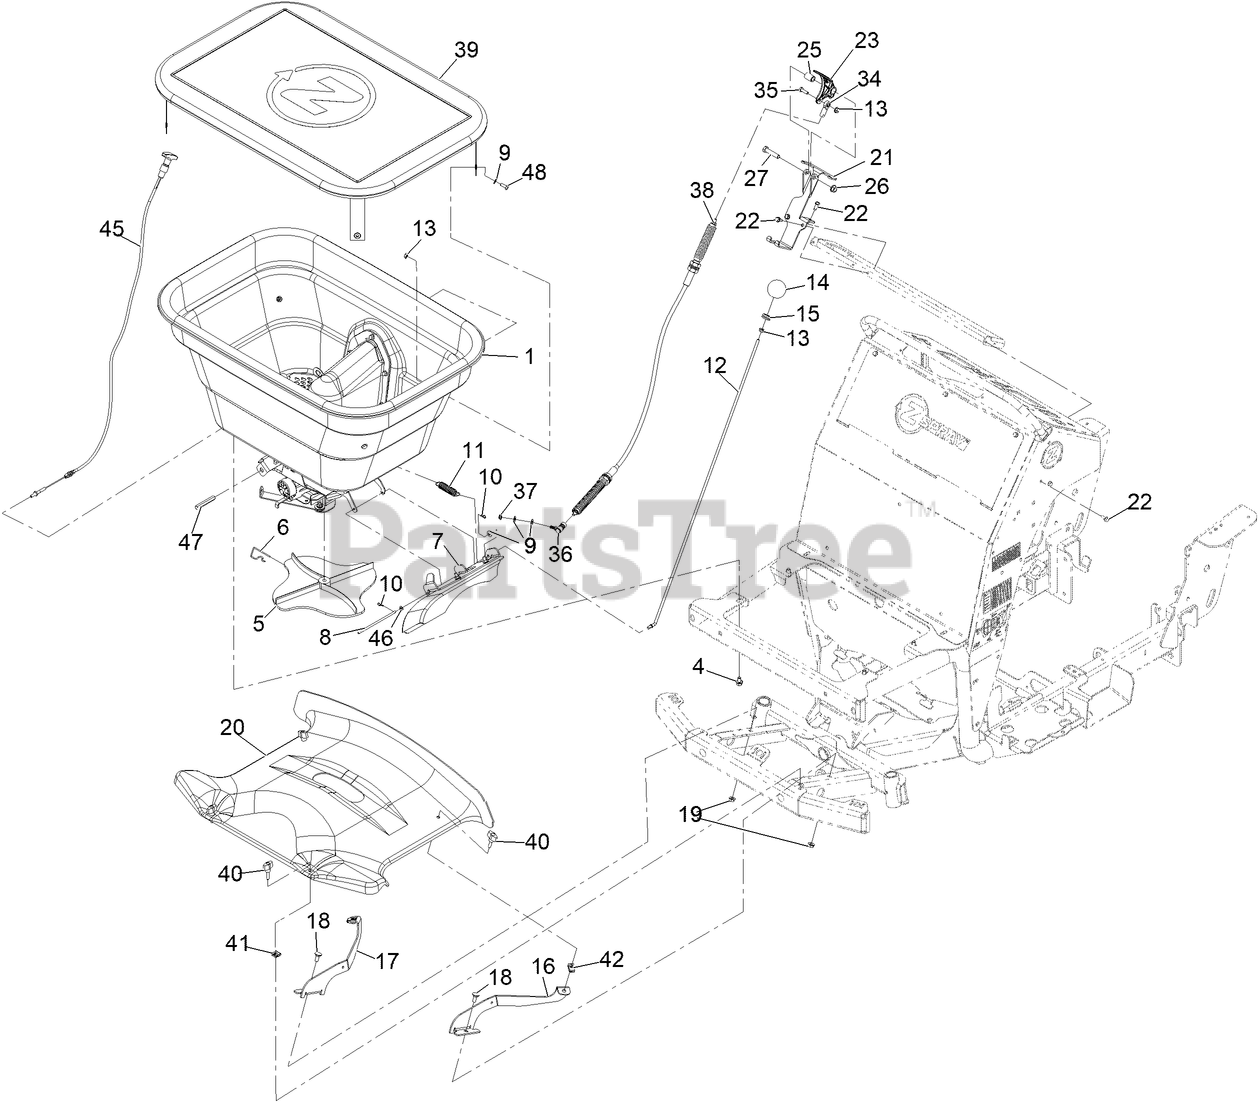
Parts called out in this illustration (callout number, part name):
1	Spreader Hopper ASM
4	SCREW-HHF
5	Spinner-Spreader
6	Clip-Spinner
7	Side Deflector ASM
8	PIN-DEFLECTOR SS
9	WASHER-FLAT
10	PIN-COTTER, HAIR
11	SPRING-EXTENSION
12	ROD-CONTROL, DEFLECTOR
14	KNOB-RATE, FLOW
15	GROMMET
16	BRACKET-COVER, FRONT (LH)
17	BRACKET-COVER, FRONT (RH)
18	SCREW-CARR
20	COVER-FRONT, SPREADER/SPR
21	Mount-Handle, Fert Gate
22	SCREW-HWH
23	Lever-Spread, Wide
27	SCREW-HH
34	ROD END-BALL JOINT
35	SCREW-HH
36	BALL-JOINT
37	NUT-HEX, NI
39	Cover-Hopper, Clear Vinyl Window
41	NUT-RETAINER, U STYLE
42	NUT-RETAINER
45	CABLE-CONTROL, TURN LOCK
46	WASHER-FLAT
47	POST-HEX, DIFFUSER GUIDE
48	SCREW-HH
